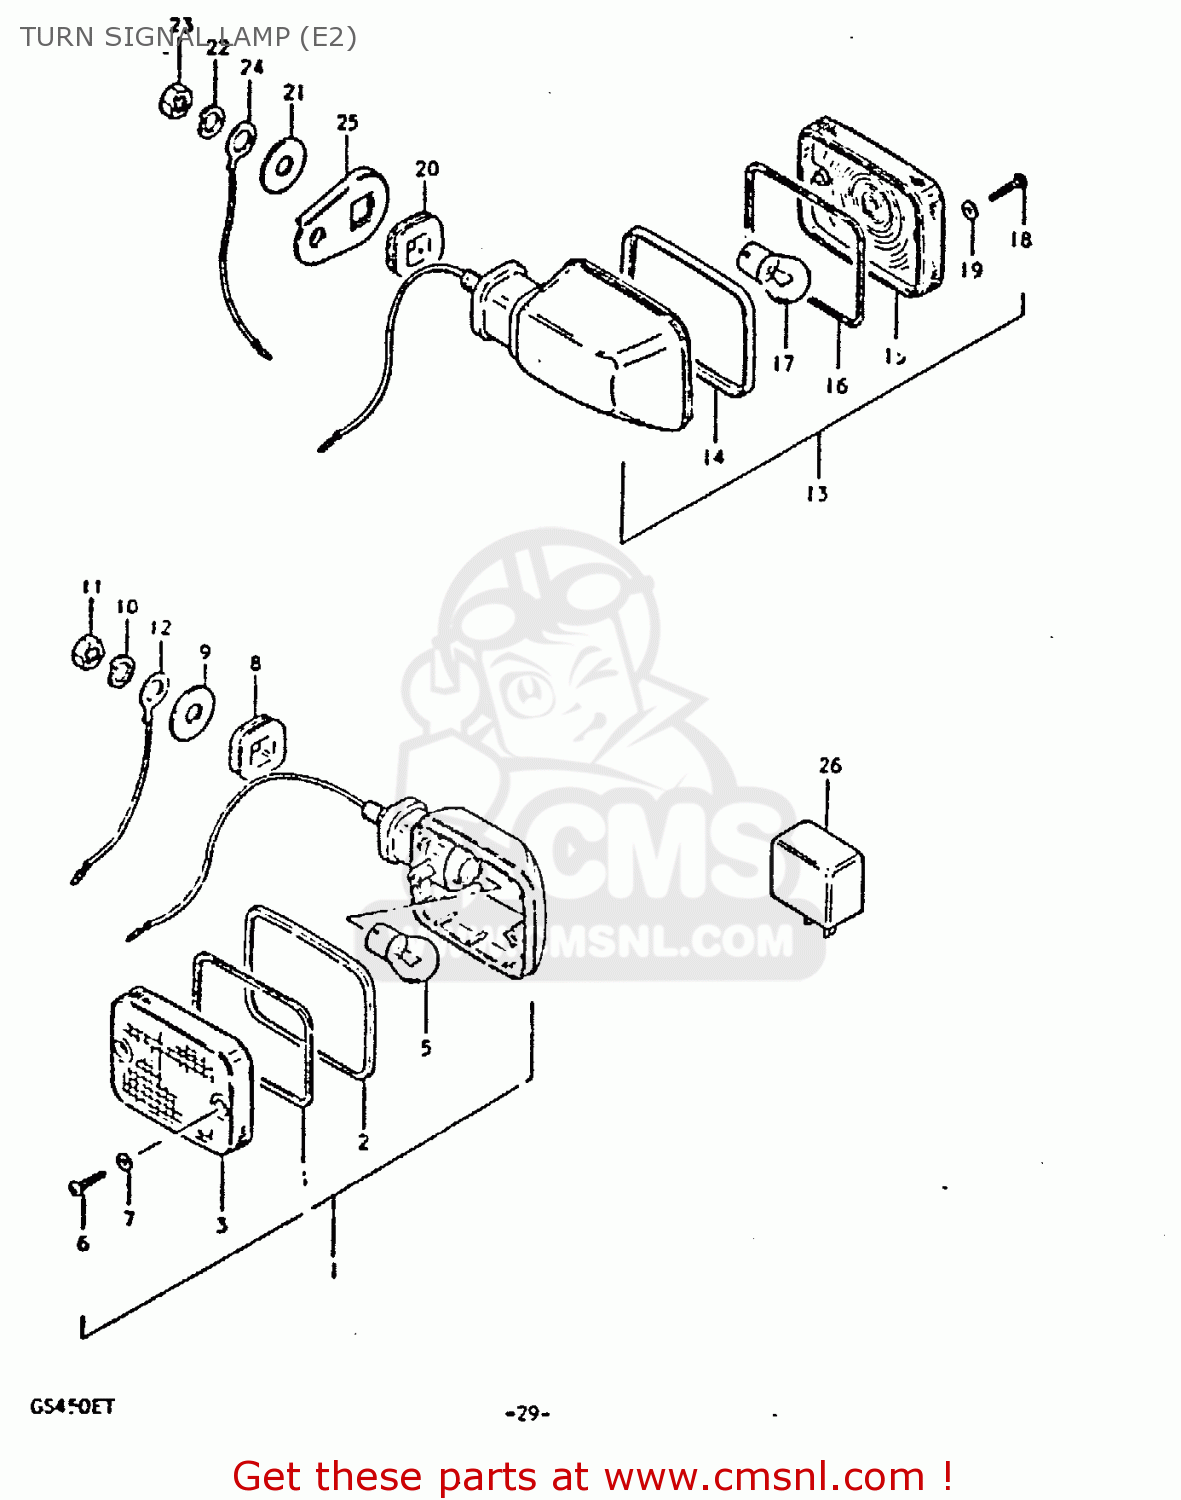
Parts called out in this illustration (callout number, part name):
1	LAMP, FRONT TURN SIGNAL
2	RIM
3	LENS
4	GASKET (NAS)
5	BULB 12V 21W
6	SCREW
7	GASKET (NAS)
8	CUSHION
9	WASHER (10.5X30X2.3)
10	LOCK WASHER
11	NUT
12	LEAD WIRE,EARTH
13	LAMP, REAR TURN SIGNAL
14	RIM
15	LENS
16	GASKET (NAS)
17	BULB 12V 21W
18	SCREW
19	GASKET (NAS)
20	CUSHION
21	WASHER (10.5X30X2.3)
22	LOCK WASHER
23	NUT
24	LEAD WIRE,EARTH
25	BRACKET,RR TURN SIGNAL LAMP
26	RELAY,TURN SIGNAL
